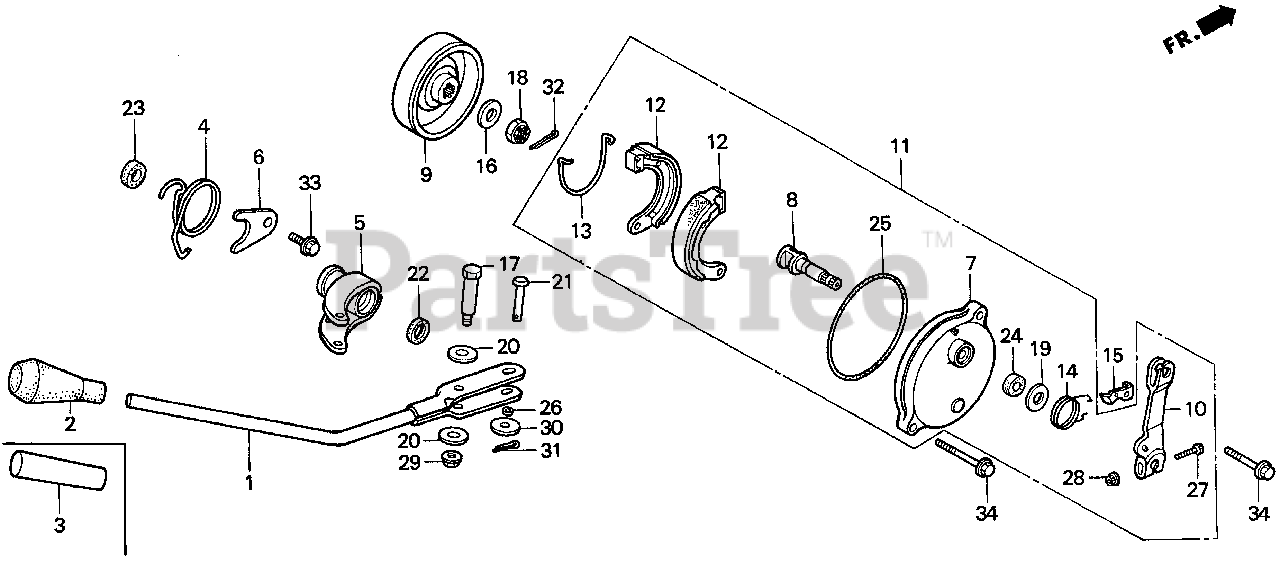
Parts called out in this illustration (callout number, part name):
1	LEVER, CHANGE
2	KNOB, CHANGE LEVER
4	SPRING, SELECT LEVER RETURN
5	HOLDER, SELECT LEVER
6	STOPPER, PLATE
7	PANEL, BRAKE
8	CAM, BRAKE
9	DRUM, BRAKE
10	ARM, BRAKE
11	PANEL ASSY., BRAKE
12	SHOE SET, BRAKE
13	SPRING, BRAKE SHOE
14	SPRING, BRAKE ARM
15	PLATE, BRAKE ARM SPRING
16	WASHER (10MM)
17	BOLT, HOLDER
18	NUT, CASTLE (10MM)
19	WASHER (10.5MM)
20	WASHER (8.3MM)
21	PIN, CHANGE LEVER
22	OIL SEAL (15X24X5)
23	DUST SEAL (15X21X3)
24	SEAL, BRAKE CAM
25	O-RING (100X2)
26	COLLAR, CHANGE JOINT
27	BOLT, HEX. (5X28)
28	NUT, FLANGE (5MM)
29	NUT, SELF-LOCK (6MM)
29	NUT, FLANGE (6MM)
30	WASHER, PLAIN (6MM)
31	PIN, COTTER (1.6X25)
32	PIN, COTTER (2.0X22)
32	PIN, COTTER (2.0X35)
33	BOLT, FLANGE (8X14)
34	BOLT, FLANGE (6X28)
